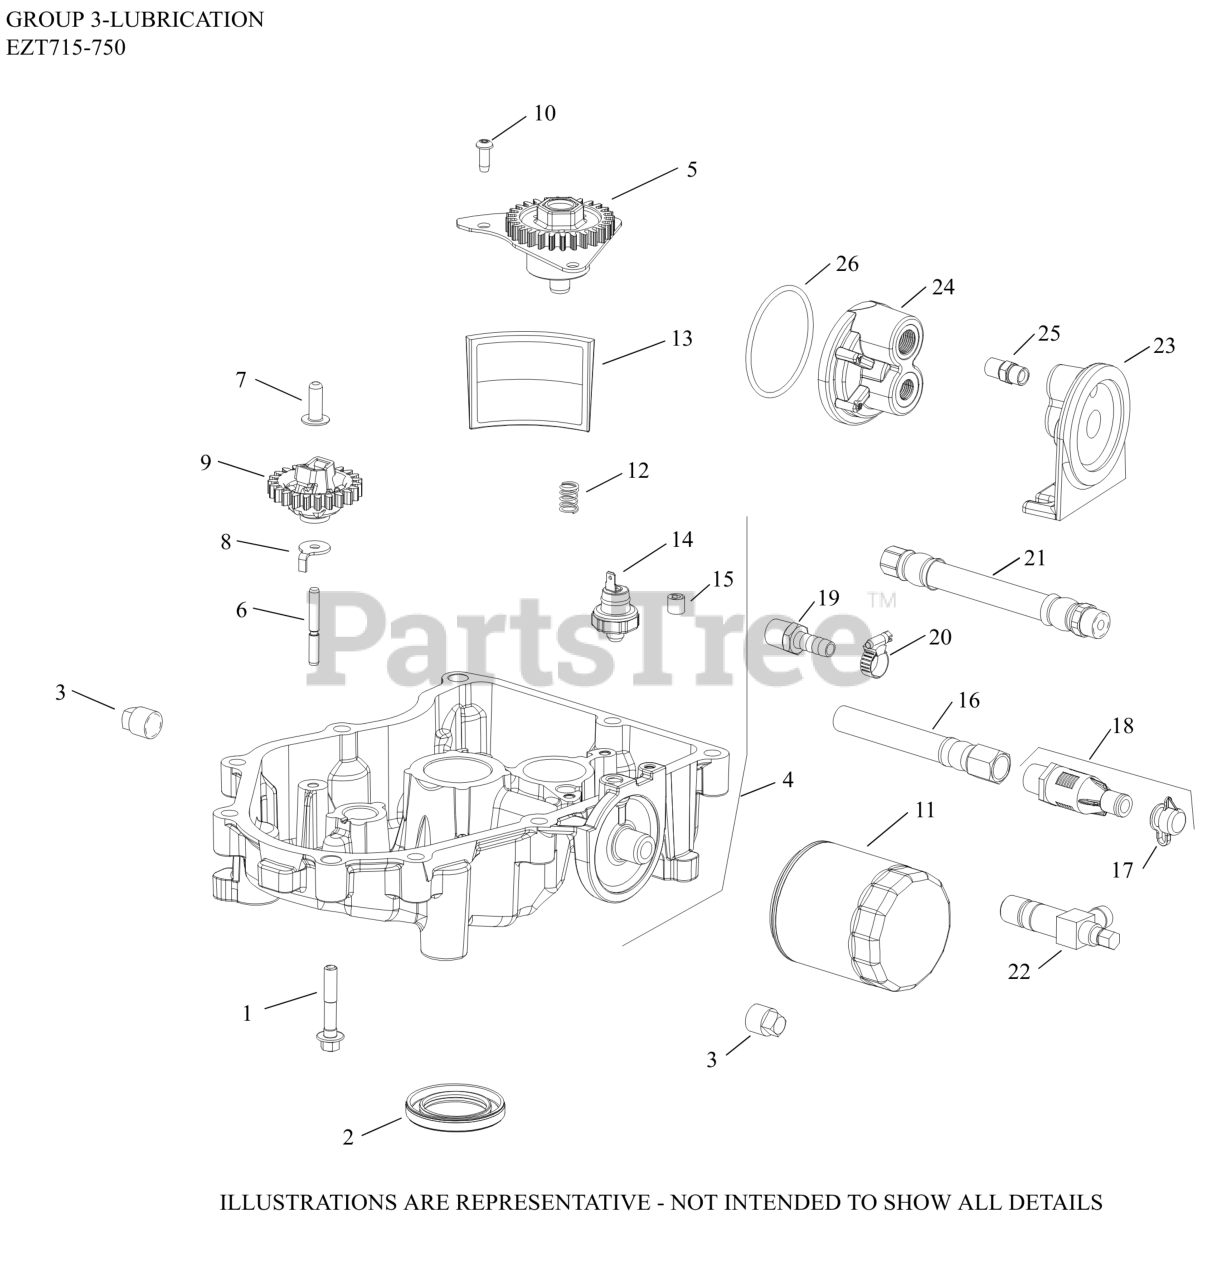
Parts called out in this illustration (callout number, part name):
1	SCREW, FLG M8X1.25X45
3	PLUG, SQ HD PIPE 3/8"
4	PAN ASSEMBLY, OIL-(#3219924S)
5	PUMP ASSEMBLY, OIL
6	SHAFT, GOVERNOR GEAR
7	PIN, GOVERNOR REGULATING
8	TAB, LOCKING
9	KIT, GOVERNOR GEAR
10	SCREW, BUTTON HEAD
11	OIL FILTER
12	SPRING, COMPRESSION
13	SCREEN, OIL
14	SENSOR, OIL PSI
